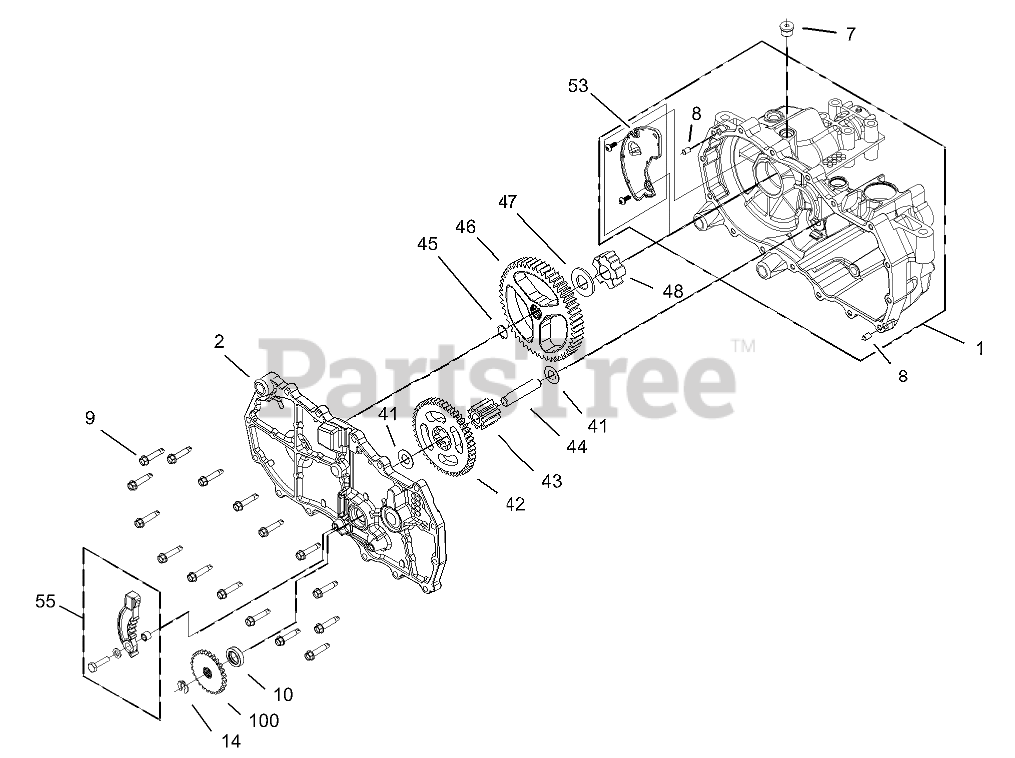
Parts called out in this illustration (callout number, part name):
1	MAIN HOUSING ASM
2	SIDE ASM
7	PLUG-THREAD, STRAIGHT
8	PIN-HYDROGEAR
9	SCREW-HHF
10	SEAL-OIL
14	RING-RETAINING, EXTERNAL
41	WASHER
42	GEAR-10T/48T
43	GEAR-JACKSHAFT, 10T
44	PIN-JACKSHAFT
45	RING-RETAINING, SPIRAL
46	GEAR-BULL, 52T
47	WASHER
48	BEARING-SLEEVE
53	EXPANSION PLATE KIT
55	BRAKE ARM KIT
100	DISC-BRAKE, COG
